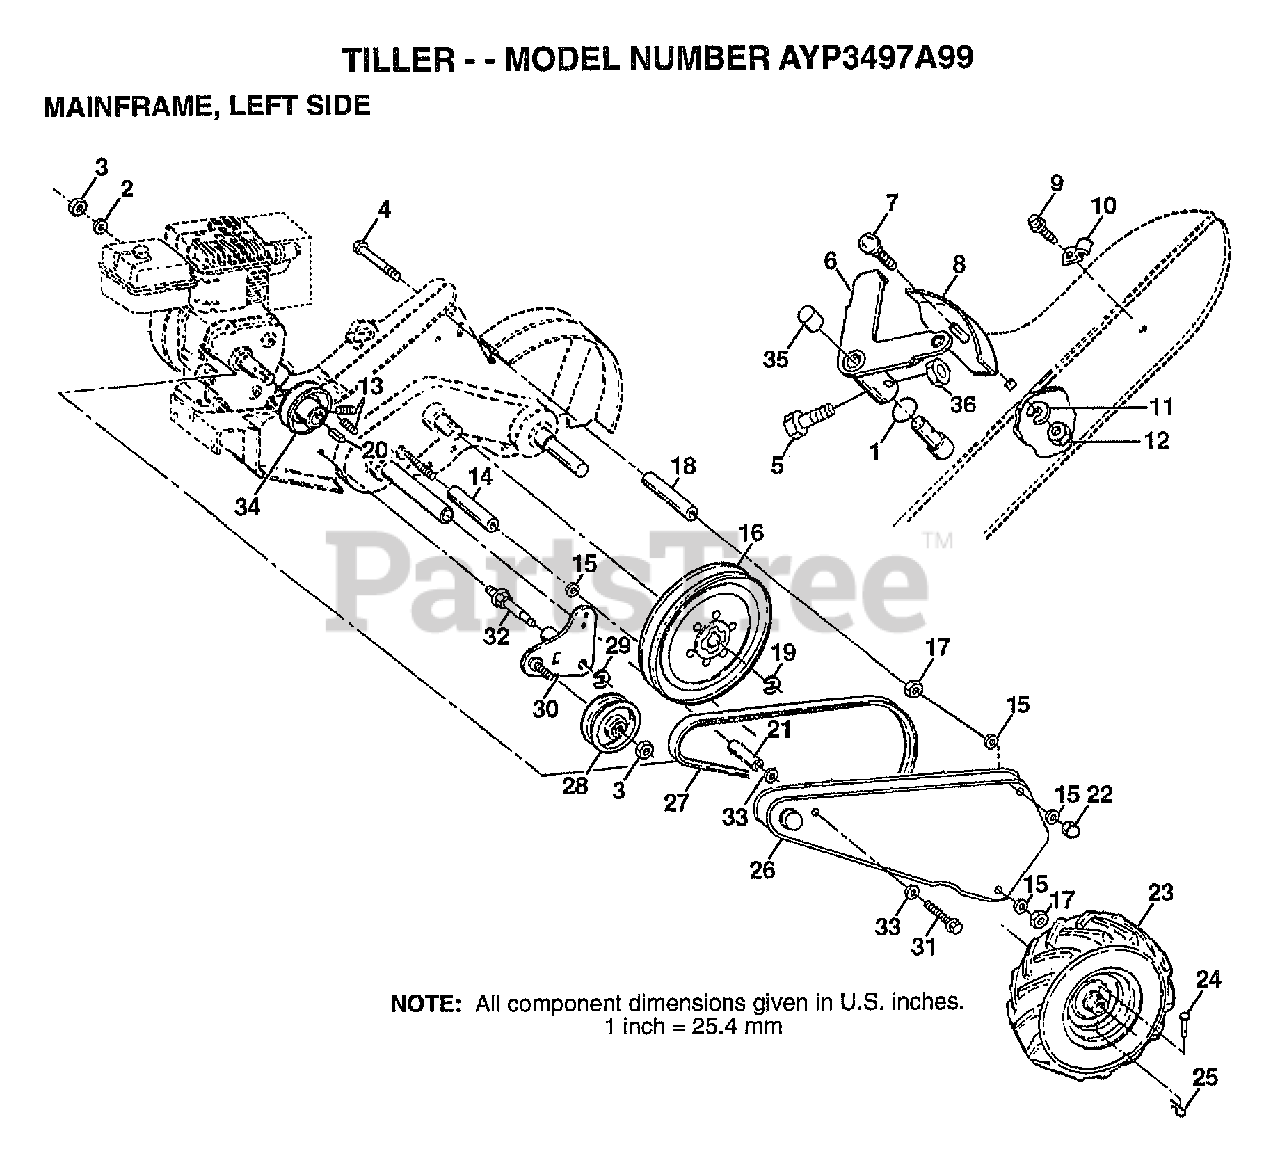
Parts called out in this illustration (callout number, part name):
1	O-RING TI
2	LOCKWASHER
3	NUT.HEX.3/8-16UNC
4	BOLT TI
5	"SCREW-LEVER,SHI"
6	LEVER ASM CRT
7	BOLT
8	PANEL TI
10	CONDIUT CLIP T
11	LOCKWASHER
13	SET SCREW
14	SPACER TI
15	WASHER
16	SHEAVE.TRANS.
17	NUT.HEX.5/16-18
18	SPACER TI
20	KEY TI
21	SPACER.SPLIT
22	NUT TI
23	TIRE TI
23	RIM.16X4X8.WHT
24	RIVET.PAN HD.1.75
25	SPRING.RETAINER
26	GUARD.BELT.GREY
27	BELT.DRIVE
28	PULLEY-IDLER TI
29	KLIP RING
30	BRACKET ASM IDLER
31	BOLT1/2-20UNF2.75
32	SHAFT.IDLER
34	SHEAVE CRT
35	CAP PLUNGER BLACK
36	LOCKNUT
